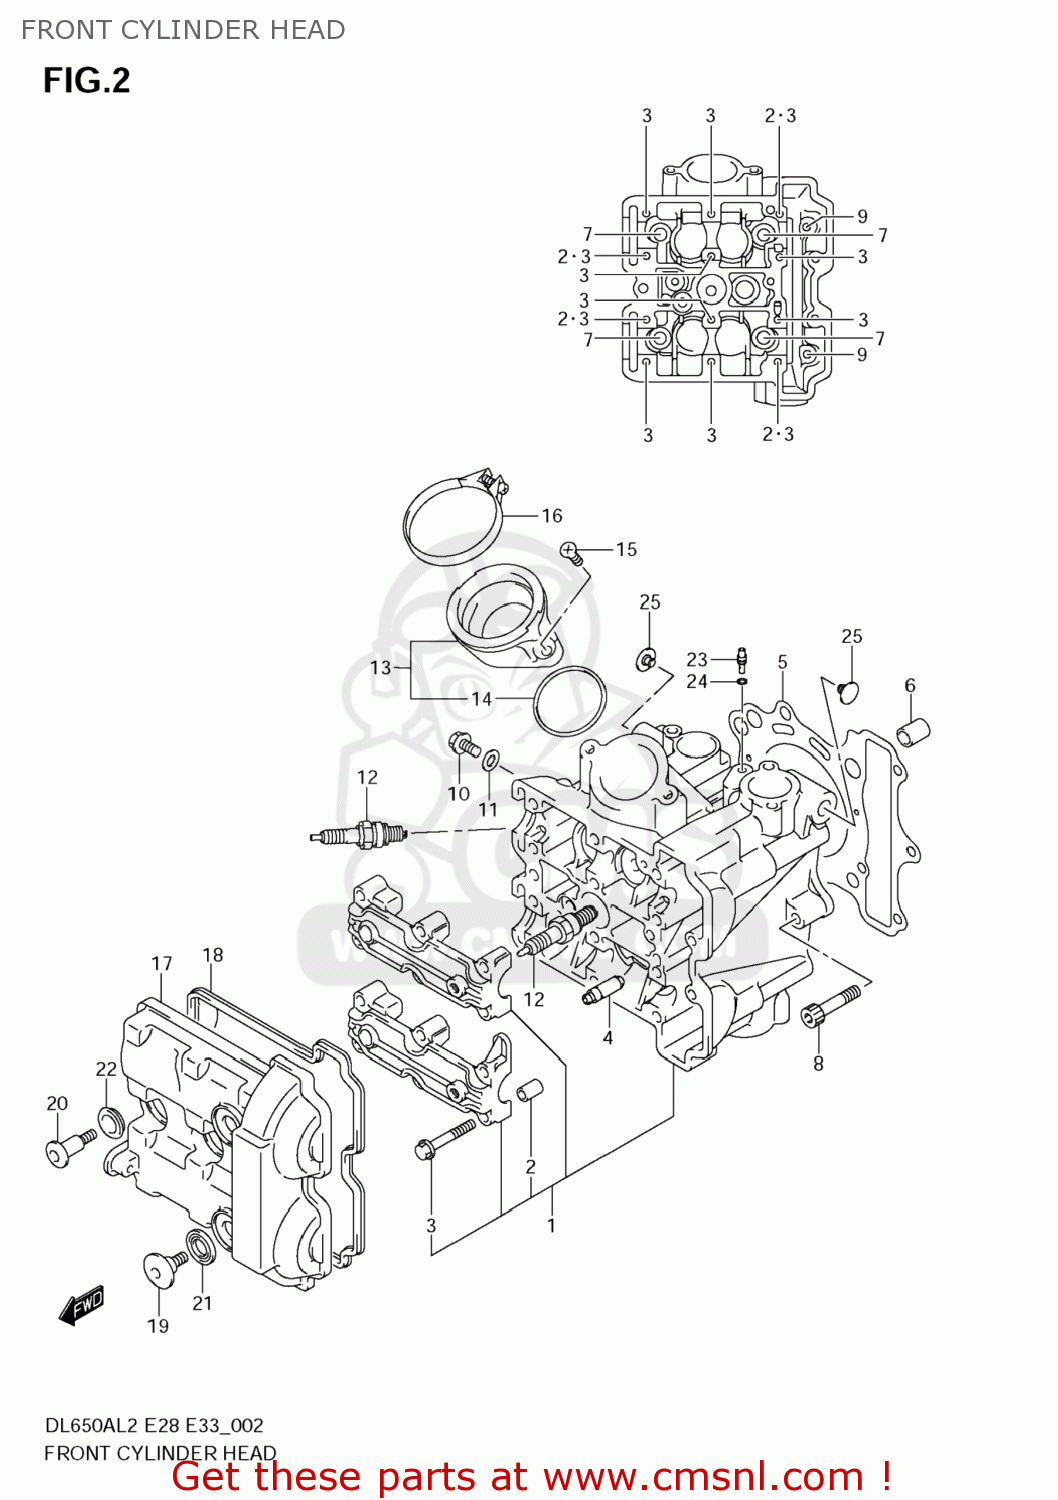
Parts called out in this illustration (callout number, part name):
1	HEAD ASSY,CYLINDER FR
2	PIN(6.2X8X11)
3	BOLT(6X40)
4	GUIDE,VALVE
5	GASKET,CYLINDER HEAD (NAS)
6	PIN
7	BOLT,CYLINDER HEAD(L:160)
8	BOLT
9	BOLT(6X70)
10	BOLT(6X12)
11	GASKET(5.8X13X1.2) (NAS)
12	PLUG,SPARK(IU24D)
13	PIPE ASSY,INTAKE FR
14	O RING(D:2.4,ID:47X42)
15	SCREW
16	CLAMP
17	COVER,CYLINDER HEAD FR
18	GASKET,CYLINDER HEAD COVER (NAS)
19	BOLT(7X17.5)
20	BOLT(7X31)
21	WASHER,CYL HEAD COVER
22	CUSHION,HEAD COVER BOLT
23	JET(8)
24	O RING(D:1.2,ID:4)
25	CAP,ENGINE MOUNTING
